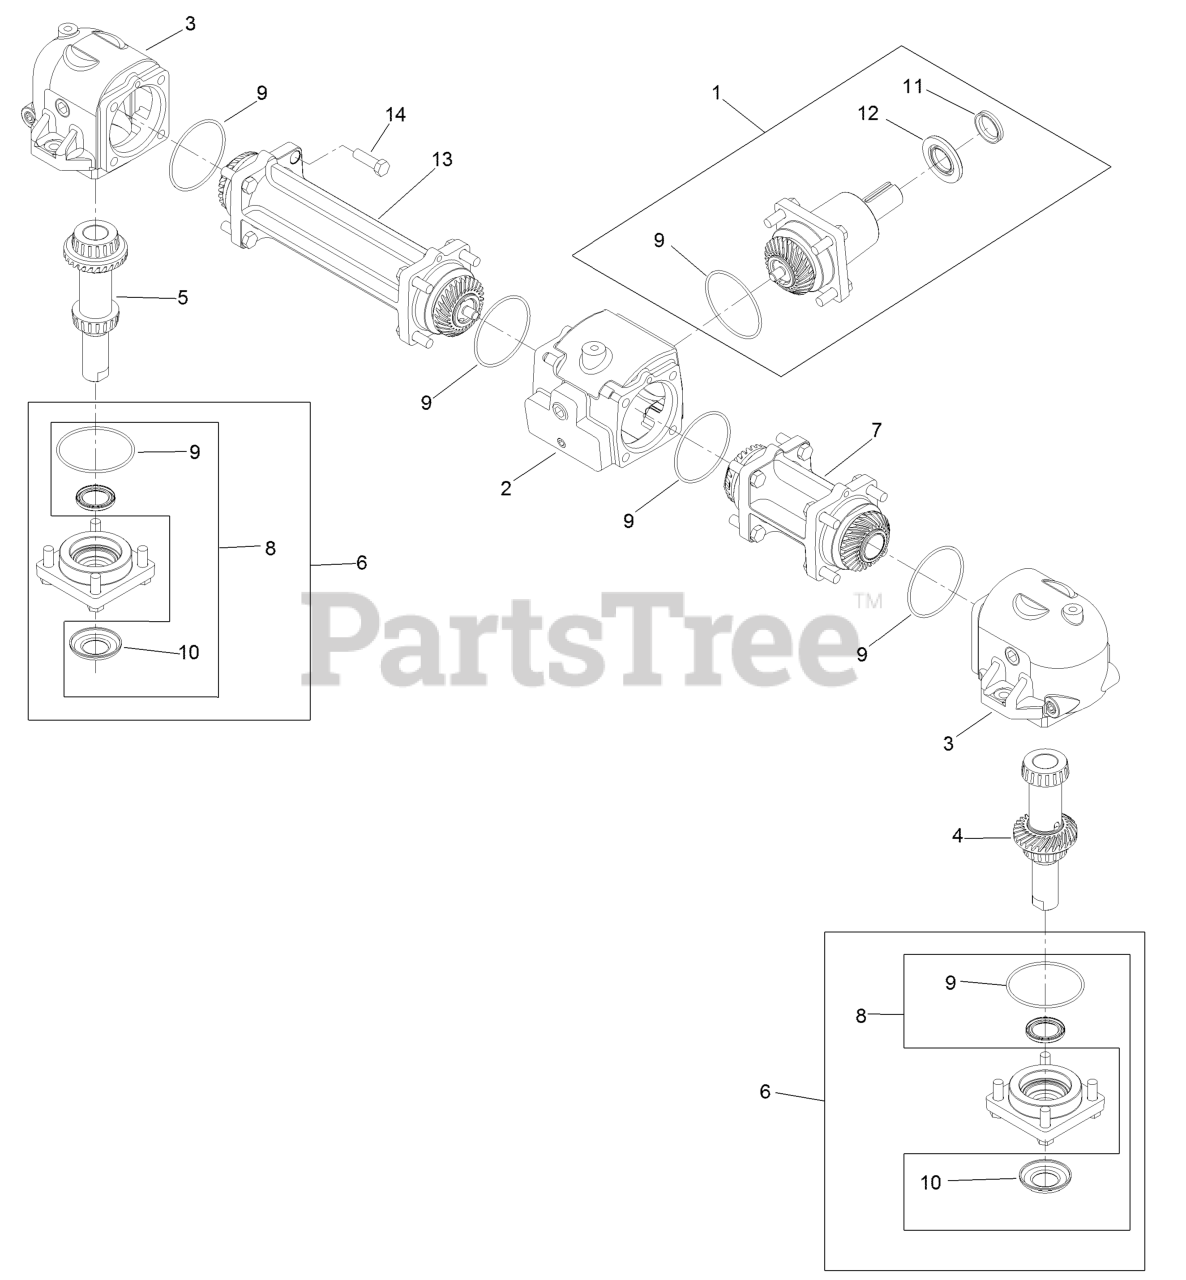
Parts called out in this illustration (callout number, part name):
1	PINION-INPUT
2	HOUSING-CENTER
3	HOUSING-END
4	OUTPUT SHAFT AND GEAR-LH
5	OUTPUT SHAFT AND GEAR-RH
6	CAP-OUTPUT
7	TUBE-CONNECTOR, SHORT
8	OUTPUT SEAL KIT
9	SEAL-O-RING
10	WASHER-CUPPED
11	SEAL-V-RING
12	SEAL-INPUT
13	CONNECTOR-TUBE, LONG
